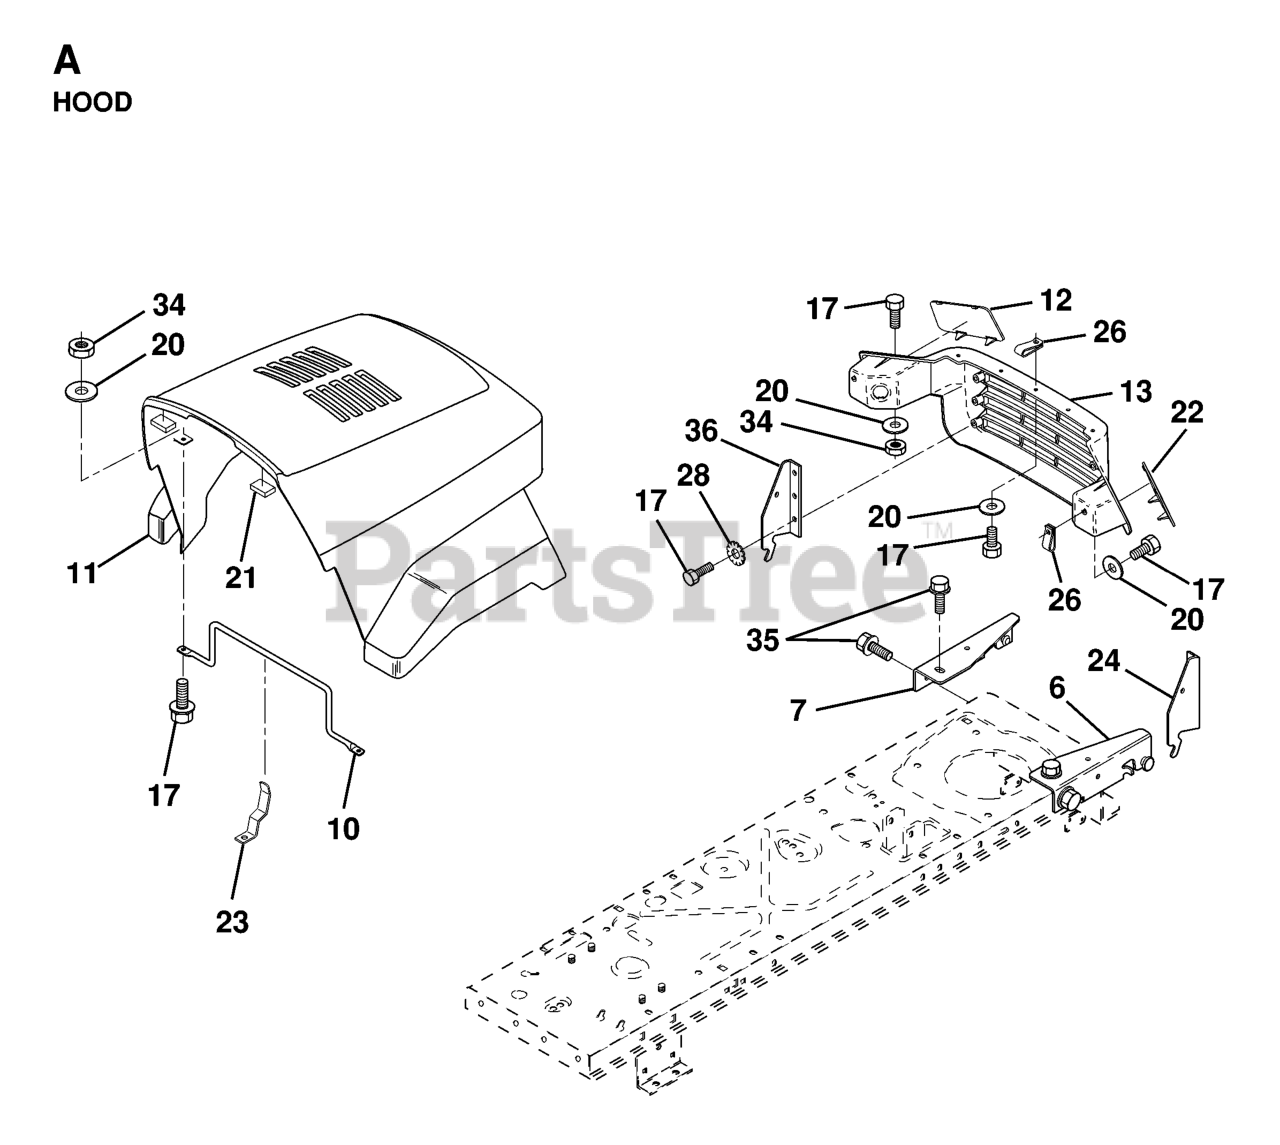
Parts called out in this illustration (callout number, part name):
6	BRACKET ASSY HOOD
7	BRACKET ASSY
10	BRACE HOOD
13	GRILL/HUSQVARNA
17	BOLT
21	BUMPER HOOD T
23	HOOD LATCH
24	BRACKET PIVOT
26	CLIP TINNERMAN
28	Washer, Lock, External Tooth 1/4
34	NUT.CROWNLOCK.1/4
35	SCREW.THDROL.5/16-18X3/4.TTY
36	BRACKET HOOD
